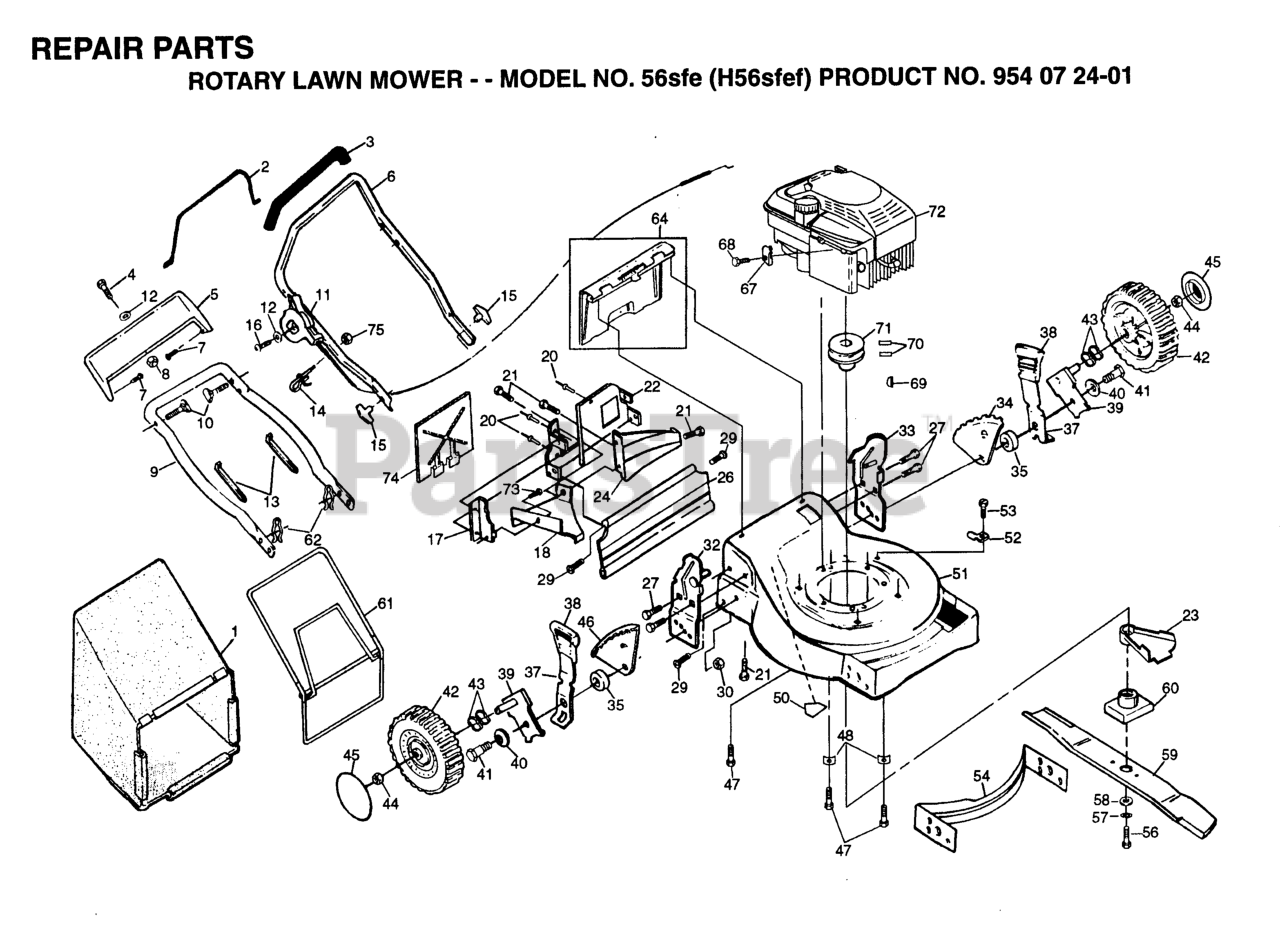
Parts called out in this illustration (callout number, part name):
1	GRASS BAG
2	CONTROL BAR
3	HANDLE GRIP
4	SCREW
5	TRIM PLATE
6	UPPER HANDLE
8	NUT
9	HANDLE, LOWER PM
10	HANDLE BOLT
11	THROTTLE CONTROL
13	TIE GUIDE
14	ROPE GUIDE
15	HANDLE KNOB
17	SIDE BAFFLE
18	DISCHARGE BAFFLE
20	RIVET BLIND
22	BACK PLATE
23	DEBRIS SHIELD
24	REAR BAFFLE
26	REAR SKIRT
27	SCREW
29	HINGE SCREW
30	LOCKNUT PM
32	HANDLE BRACKET RH
33	HANDLE BRACKET LH
34	WHEEL ADJ BRKT RF-LR
35	SPACER PM
37	SELECTOR SPRING
38	SELECTOR KNOB
39	AXLE ARM ASSY FT
40	WASHER.BELLEVILLE (3 2 LB)
41	BOLT
42	WHL & TIRE ASSEMBLY
43	WAVE WASHER
44	HEX FLANGE LOCKNT
46	WHEEL ADJ BRKT RR-LF
47	BOLT
48	WASHER.ENGINE.BZP
50	DECAL HYT
51	HOUSING (INCL KEY #50)
52	GUIDE CLIP PM
53	TAPPING SCREW
54	FRONT BAFFLE
56	SCREW, HEX HD 3/8-24 X 1-3/8
57	LOCKWASHER
58	WASHER,HARDEN
60	BLADE ADAPTOR
61	CATCHER.FRAME.WALK
62	HAIRPIN COTTER
64	REAR DOOR ASSEMBLY
67	WASHER
68	SCREW.HEX.HEAD.WASHER.10-16
69	HI PRO KEY PM WSL
71	ENGINE.PULLEY.FWG
74	MULCHER PLATE
75	NUT
